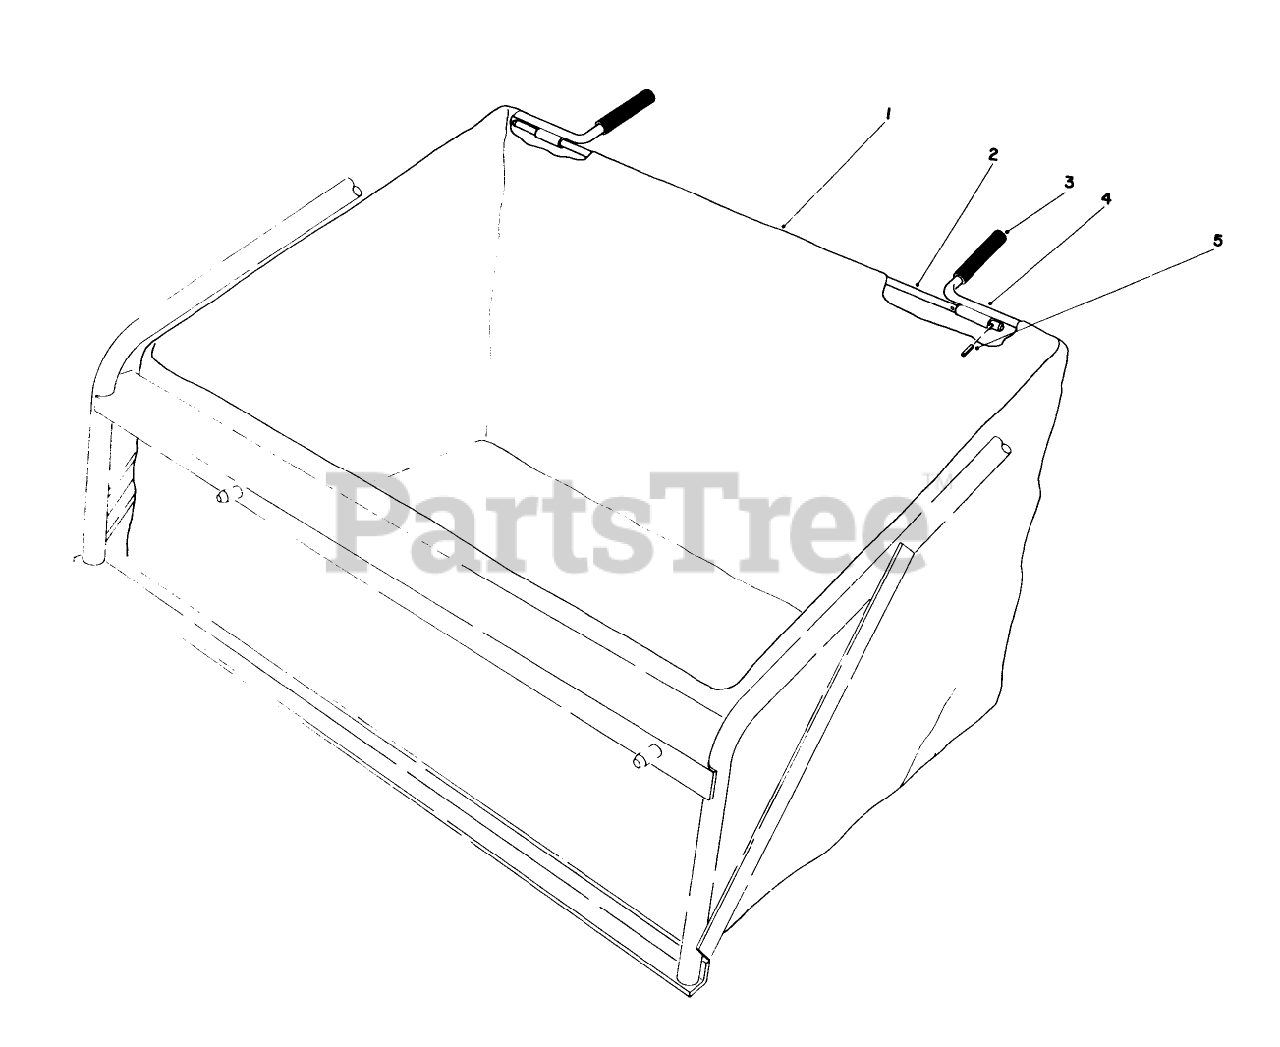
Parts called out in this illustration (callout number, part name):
1	Bag-Leaf Catcher
2	Rod-Bag Frame
3	Grip-Leaf Bag Handle
4	Bag Frame
5	PIN-ROLL
